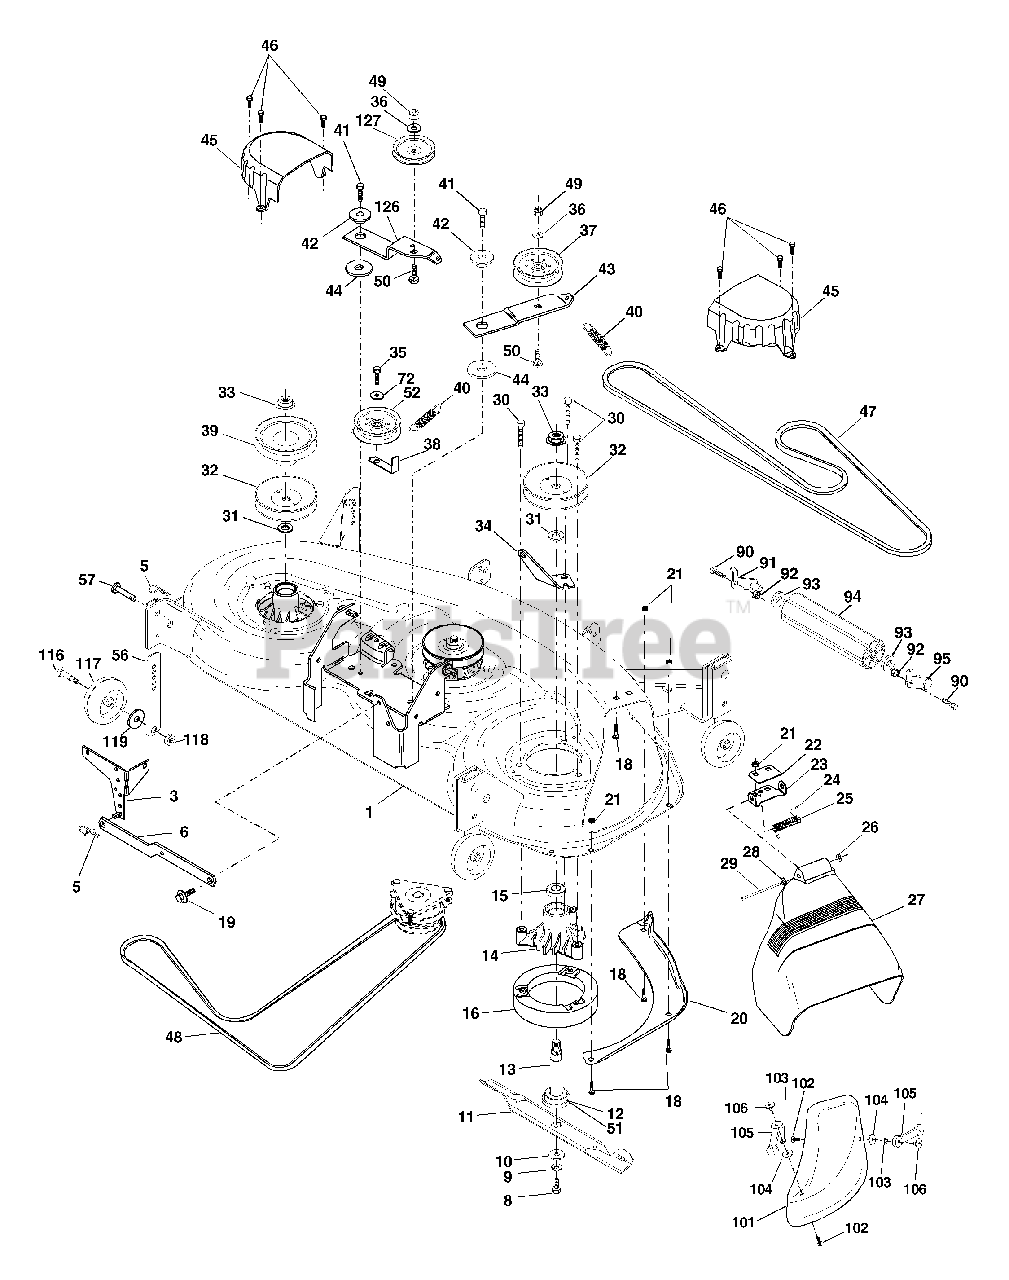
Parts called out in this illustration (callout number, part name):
1	Deck Asm., Mower 46"
3	Bracket Asm., Sway Bar
5	Retainer Spring
6	Arm, Suspension, Rear (Sway Bar)
8	Bolt, Patched 3/8-24 x 1-1/4 Gr. 8
9	Washer, Lock Hvy., Unplated 3/8
10	Washer, Hard Blade, Mower Vented
11	Blade, 46" Hi Perf
11	Blade, 46" Mulching
12	Bearing, Ball, Mandrel #6204
13	Shaft Asm. w/Lower Bearing
14	Housing, Mandrel
15	Bearing, Ball, Mandrel
16	Stripper, Mower Round
18	Bolt, Carriage 5/16-18 x 5/8
19	Bolt, Hex Head, Shoulder 5/16-18
20	Baffle, Vortex Mower 46"
21	Nut, Crownlock 5/16-18 UNC
22	Stiffener, Bracket
23	Bracket, Deflector
24	Cap, Sleeve
25	Spring, Torsion, Deflector
26	Nut, Push
27	Shield, Deflector Mower
28	Washer 11/32 x 5/8 x 16 Ga.
29	Rod, Hinge
30	Screw, Wsh Head, Thdroll
31	Washer, Spacer Mower Vented
32	Pulley, Mandrel
33	Nut, Flg. Top Lock Cntr. 9/16
34	Anchor, Spring Deck 46"
35	Screw, Thdroll 3/8-16 x 1-3/4 Tytt
36	Washer 13/32 x 13/16 x 16 Ga.
37	Pulley, Idler, Flat
38	Keeper, Belt, Idler
39	Pulley, Idler, Driven
40	Spring, Secondary 44/46/50 Vent
41	Screw 3/8-16 x 1-1/4
42	Spacer, Retainer
43	Arm, Idler Secondary
44	Washer, Hardened
45	Cover, Mandrel Deck
46	Screw, Thdroll. 1/4-20 x 5/8
47	V-Belt, Mower, Secondary
48	V-Belt, Mower, Primary
49	Nut, Crownlock 3/8-16 UNC
50	Bolt, Carriage 3/8-16 x 1-1/2 Gr. 5
51	Washer, Felt
52	Pulley Idler 46 Pri. Drive
56	Bar Adjusting Gage wheel
57	Pin Head Rivet
72	Washer 13/32 x 1 x 16 Ga.
90	Bolt, Fin, Hex 3/8-16 UNC x 1
91	Bracket, Asm Noseroller, LH
92	Nut, Lock, Hex w/Ins 3/8-16UNC
93	Washer 17/32 x 7/8 x 16 Ga.
94	Roller, Nose 38 & 42
95	Bracket, asm Noseroller RH
101	Cover Mulcher 46" Black
102	Screw Phillips Truss Head
103	Washer Lock #10
104	Washer #10
105	Latch Asm mulch/Bagger
106	Nut Weld
116	Bolt, Shoulder
117	Gauge Wheel
118	Nut, Centerlock 3/8-16 UNC
119	Washer 3/8 x 7/8 x 14 Ga.
126	Arm, Idler, Primary Deck 46"
127	Pulley, Idler, V-Groove Dim. 4.25
